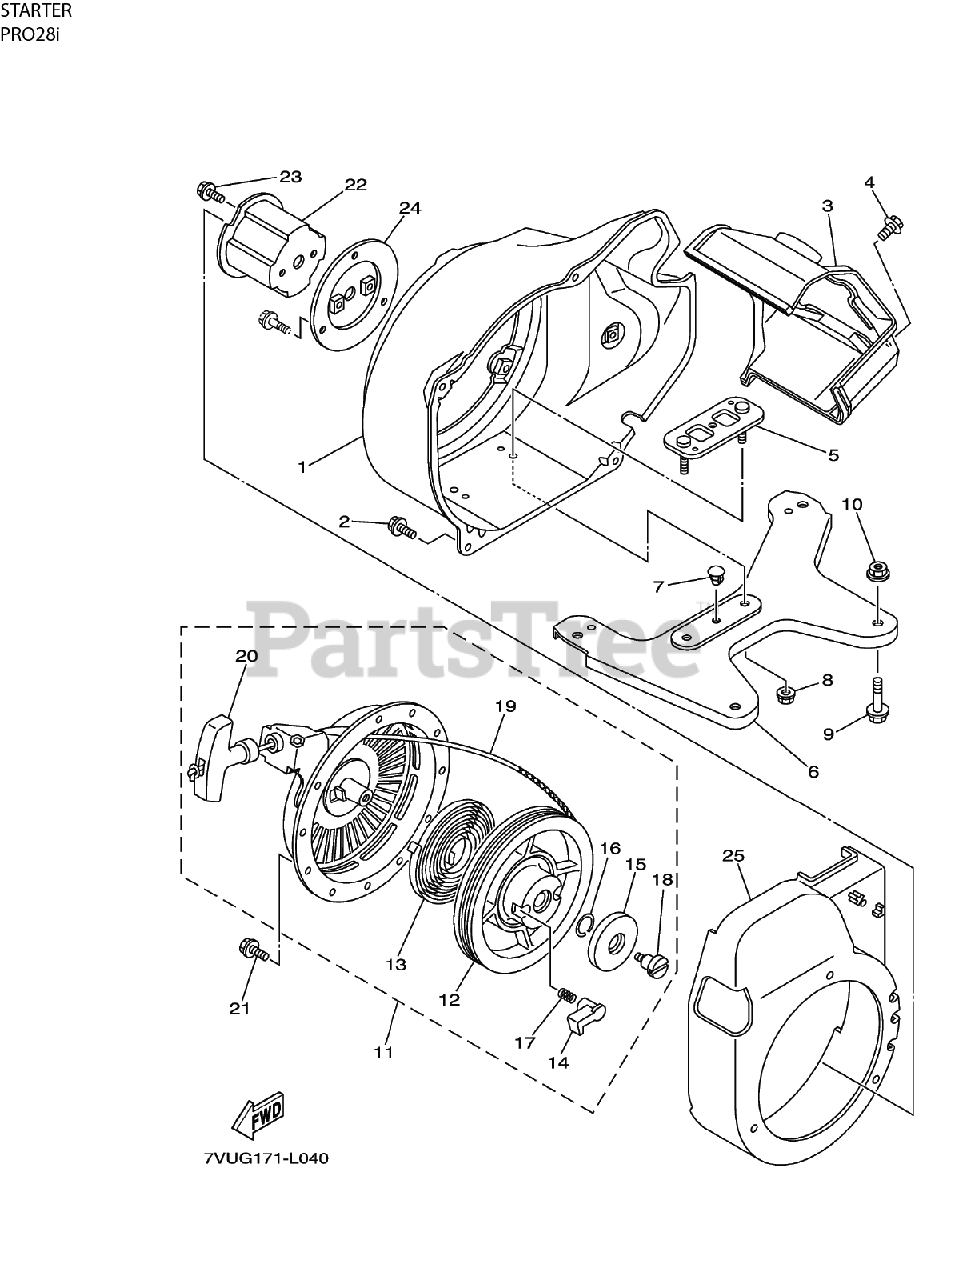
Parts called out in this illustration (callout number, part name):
1	HOUSING, BLOWER - CASE, FAN
2	SCREW - BOLT FLANGE
3	BAFFLE - AIR SHROUD, CYLINDER
4	SCREW - BOLT FLANGE
6	BRACKET, ENGINE
8	NUT, FLANGE
9	SCREW - BOLT FLANGE
10	NUT, FLANGE
11	RETRACTABLE STARTER ASSEMBLY
12	PULLEY, STARTER - DRUM SHEAVE
13	SPRING, STARTER
14	PAWL, DRIVE
15	PLATE, DRIVE
16	SPRING, FRICTION
17	SPRING, RETURN
19	ROPE, STARTING - WIRE
20	HANDLE, STARTER
21	SCREW - BOLT FLANGE
22	CUP, STARTER
23	SCREW - BOLT FLANGE
25	COVER, AIR CLEANER - COVER, FAN CASE
